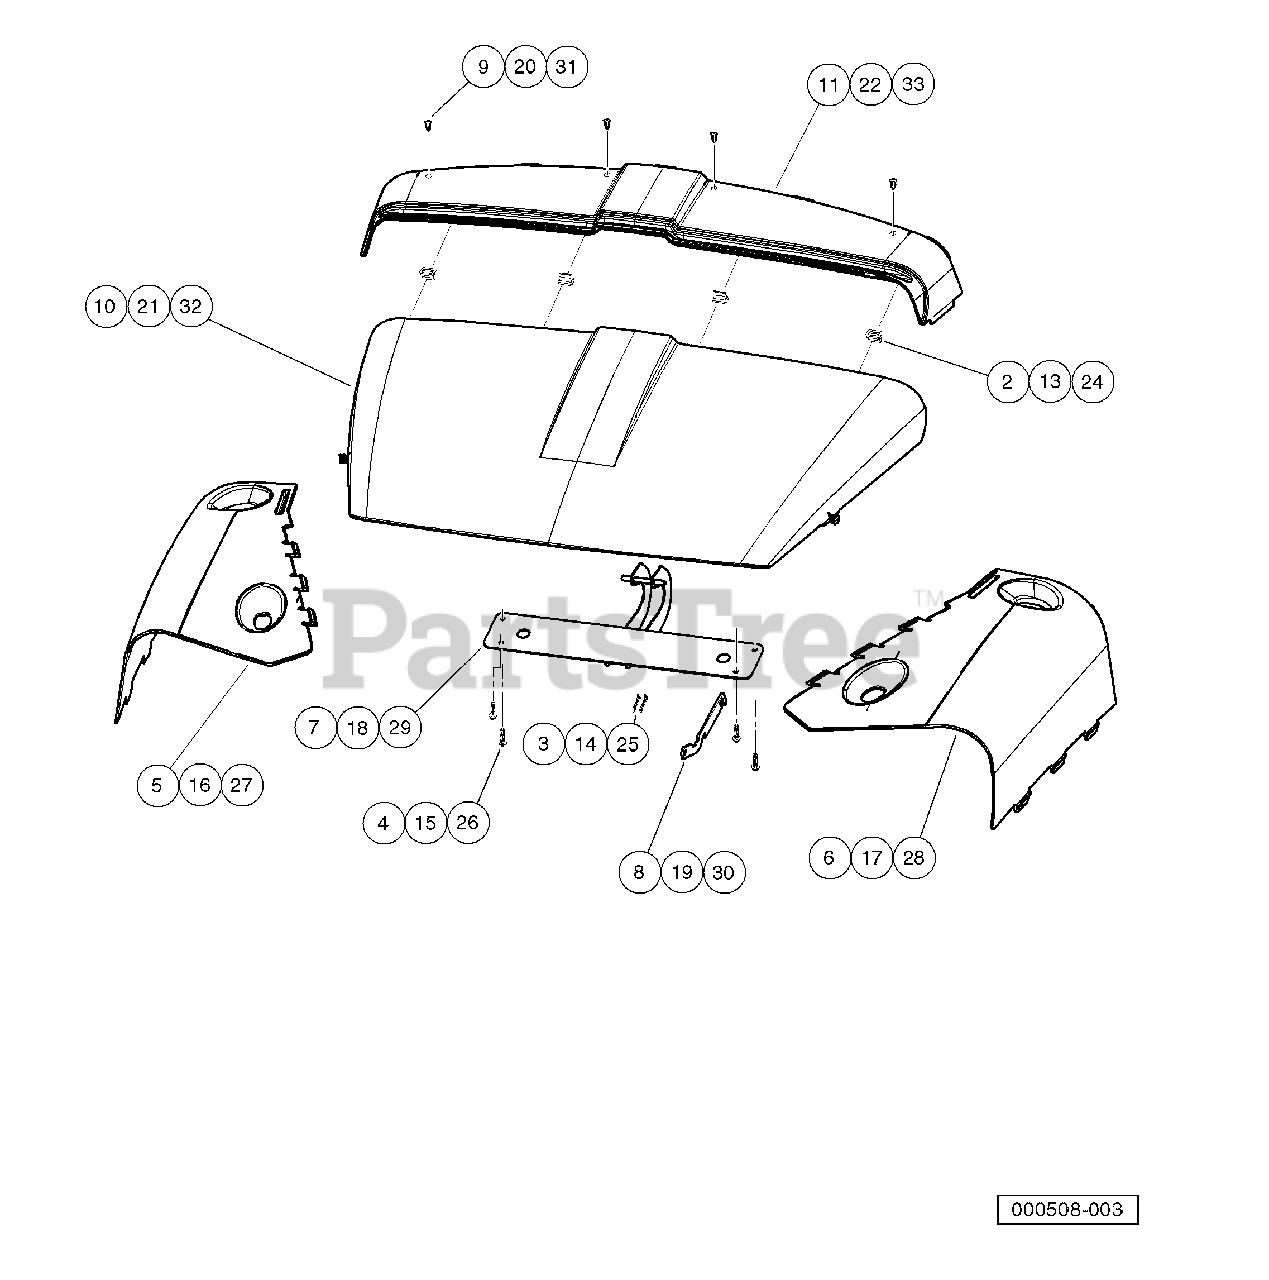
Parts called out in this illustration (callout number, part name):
1	Option, Color, Huv, Camo
2	Clip-body-trim
3	Pin, Bow Tie Locking - .072
4	Screw,m6,torx,interlock,thread
5	Panel, Cowl, Passenger-Side, Real Tree Camo
6	Panel, Cowl, Driver-Side, Real Tree Camo
7	Weldment, Hinge, Hood
8	Prop, Hood
9	Rivet, Removable, Tuflok 1/4"
10	Hood, Design B, Moff
11	Panel, Cowl, Upper, B,moff
12	Option, Color, HUV, Orange
13	Clip-body-trim
14	Pin, Bow Tie Locking - .072
15	Screw,m6,torx,interlock,thread
16	Panel, Cowl, Ps, Orange
17	Panel, Cowl, Drv, Orange
18	Weldment, Hinge, Hood
19	Prop, Hood
20	Rivet, Removable, Tuflok 1/4"
21	Hood, Design B, Orange
22	Panel, Cowl, Upper, B, Orange
23	Option, Color, Huv, Olive Grm
24	Clip-body-trim
25	Pin, Bow Tie Locking - .072
26	Screw,m6,torx,interlock,thread
27	Panel, Cowl, Ps, Olive Green
28	Panel, Cowl, Drv, Olive Green
29	Weldment, Hinge, Hood
30	Prop, Hood
31	Rivet, Removable, Tuflok 1/4"
32	Hood, Design B, Olive Grn
33	Panel, Cowl, Upper, B, Olv Grn
